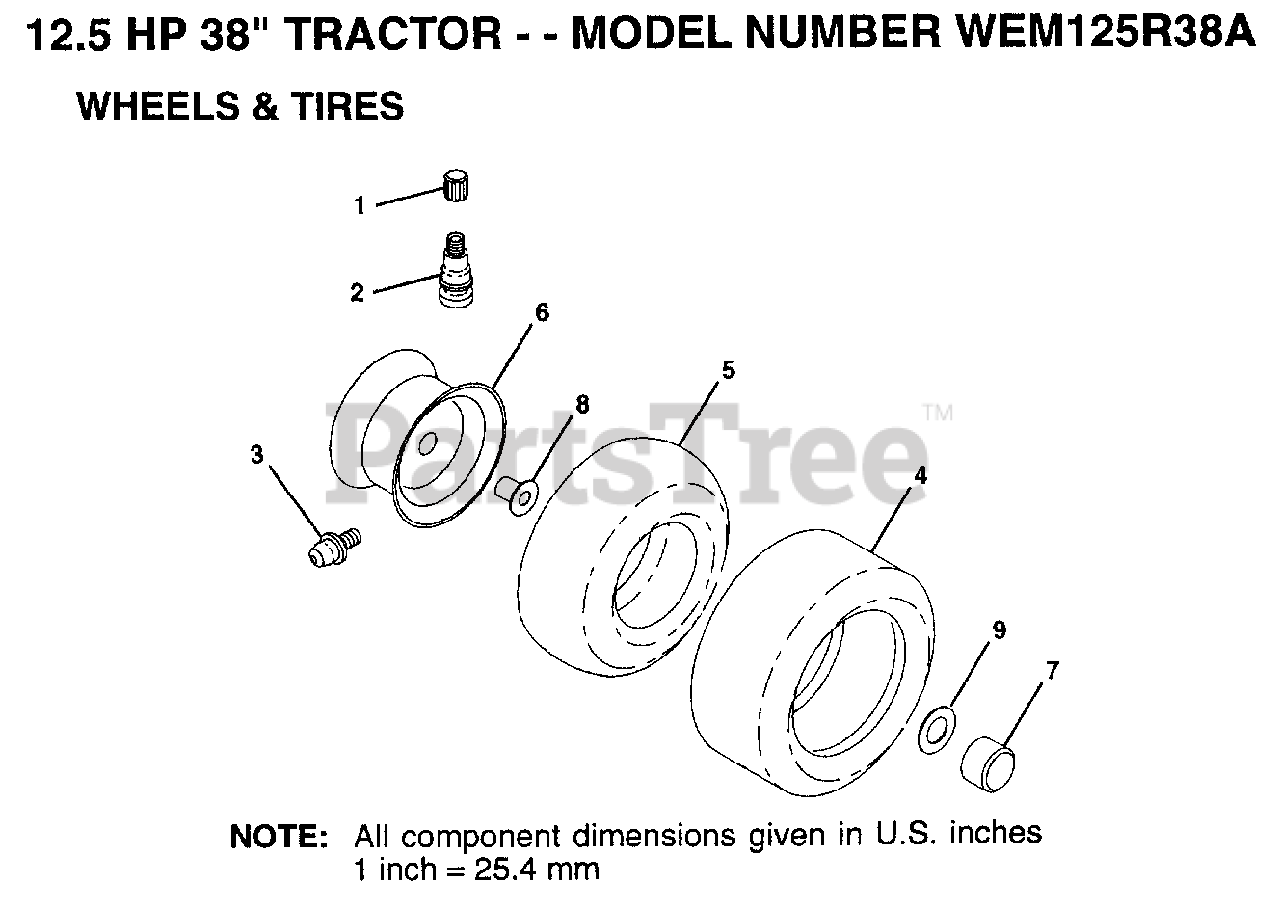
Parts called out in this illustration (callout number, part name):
1	VALVE CAP
2	VALVE STEM LT
3	FITTING LT
5	TUBE.5.3/4.5/6
5	TUBE.16X6.5/7.5-8
6	"RIM REAR 8"""
7	HUB CAP
8	"FLANGE, BEARING"
9	WASHER
